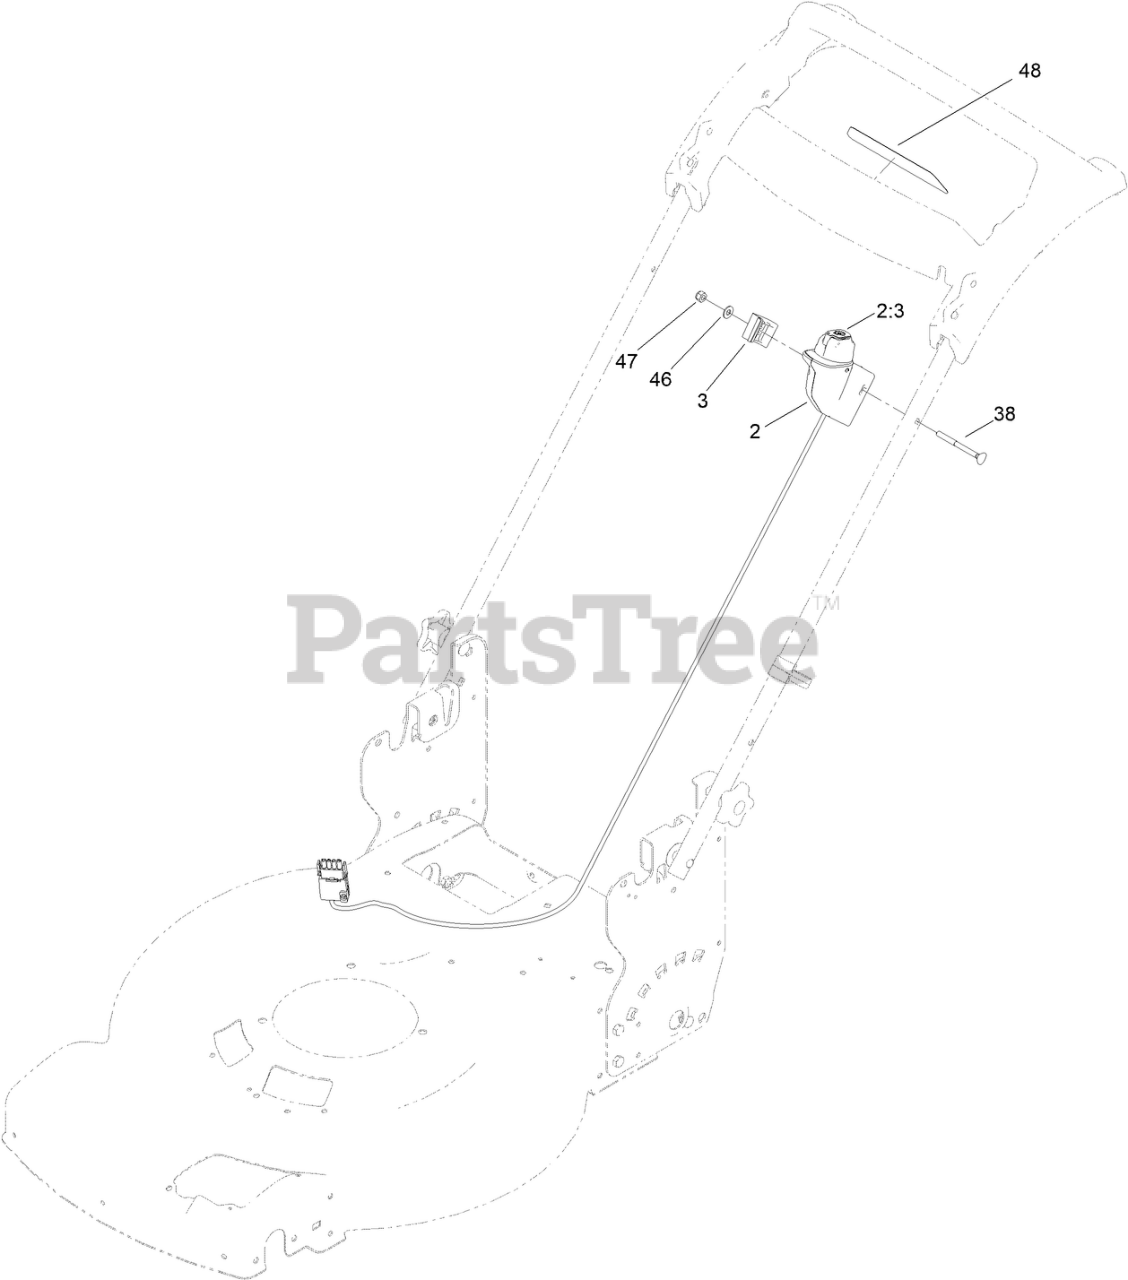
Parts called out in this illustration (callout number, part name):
2	SWITCH-STARTER ASM
2:3	STARTER BUTTON SERVICE ASM
3	CLAMP-CABLE
38	SCREW-HANDLE
46	WASHER-FLAT
47	NUT-LOCK, NI
48	DECAL-CONTROLS (60V)
